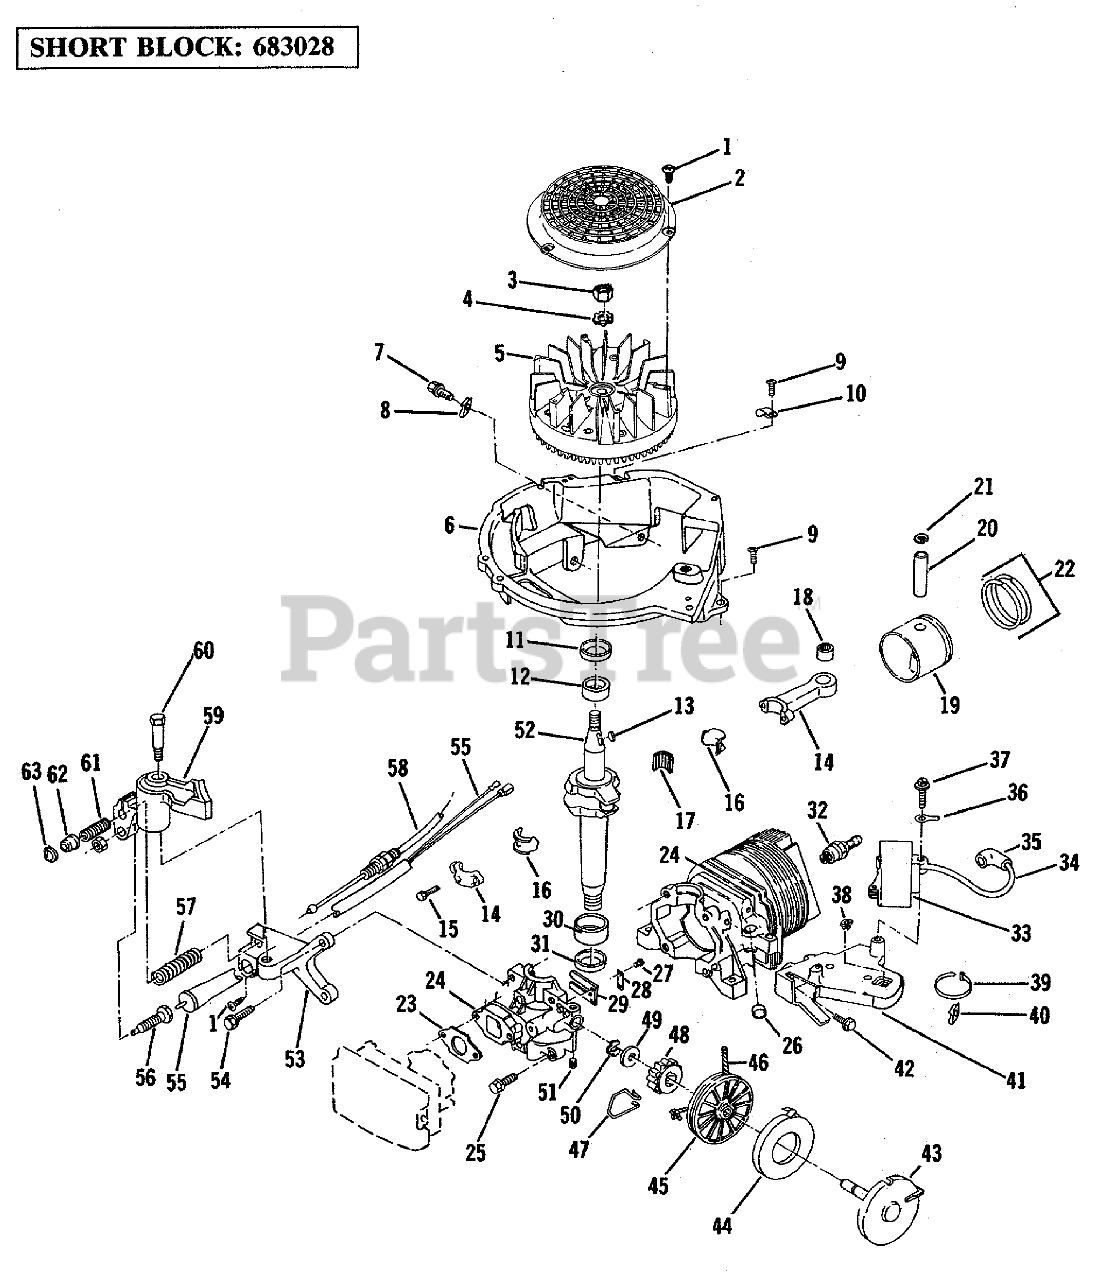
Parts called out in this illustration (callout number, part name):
1	SCREW F
2	SCREEN F'WHEEL S
3	NUT
7	SCREW-SEMS
9	SCREW F
12	BEARING V
13	KEY
15	SCREW-HSH
16	LINER ASM
18	BEARING AY F
21	RING-RETAINING
23	GASKET CARB S
25	SCREW S
26	PLUG-CORE VF
28	PLATE-BACKUP, REED
30	BEARING V
31	SEAL-OIL
34	HT LEAD&COVER XEV
36	TERMINAL S
38	NUT-CLIP
41	BRACKET S
45	PULLEY STARTER S
46	ROPE-STARTER
47	SPRING F
49	WASHER S
53	BRACKET-BRAKE F
56	PLUNGER S
57	SPRING-BRAKE
58	CONTROL CABLE AY
59	Brake Assembly
61	SPRING
62	ACTUATOR-LEVER, BRAKE
63	RETAINER S
